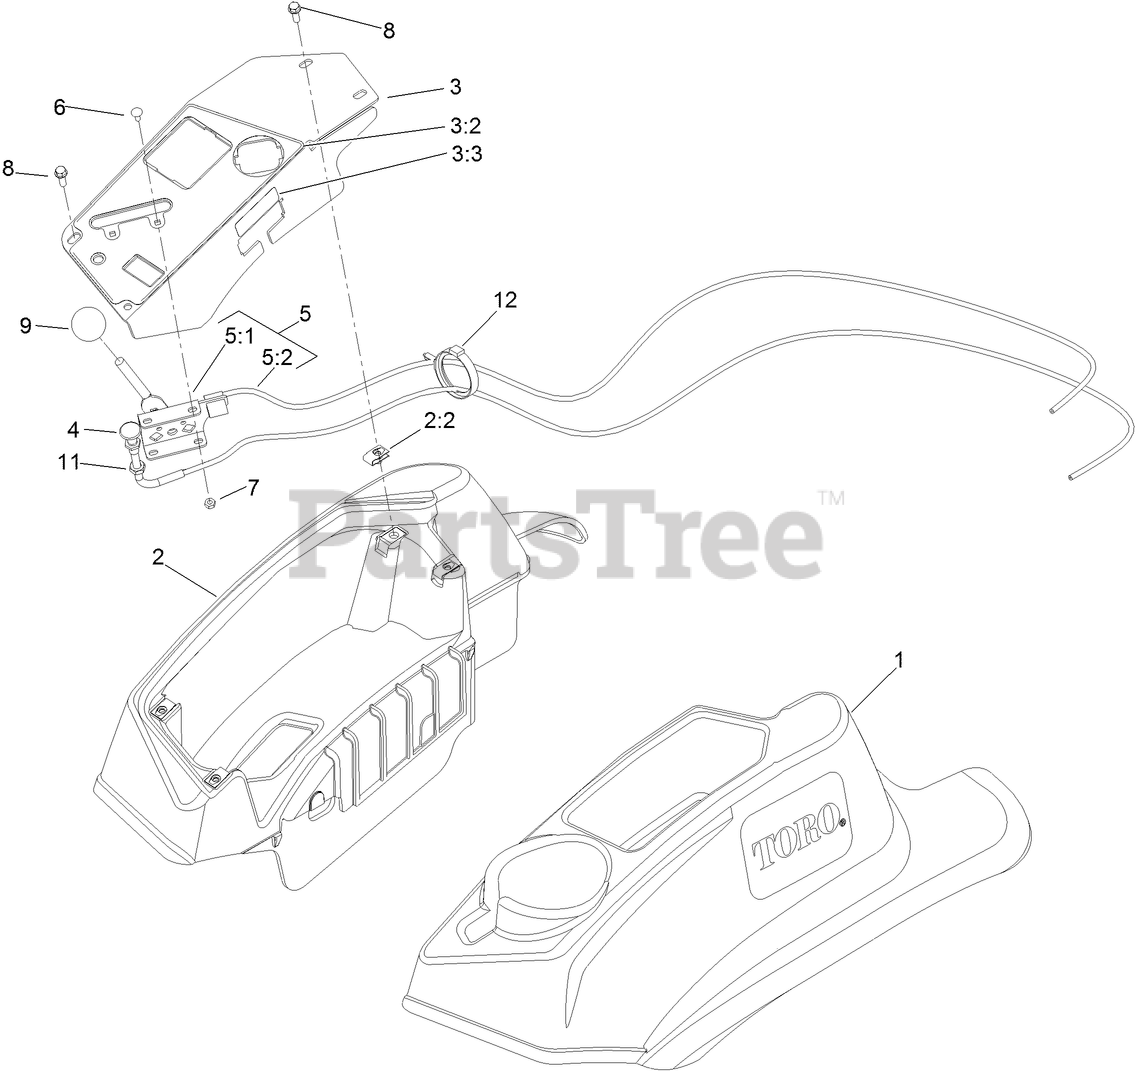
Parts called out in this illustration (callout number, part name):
1	CONSOLE-LH
2	RH CONSOLE ASM
3	CONTROL PANEL ASM
3:2	DECAL-CONTROL PANEL
3:3	DECAL-FUSES
4	CONTROL-CHOKE
5	THROTTLE CONTROL ASM
5:1	LEVER-THROTTLE
5:2	CABLE-THROTTLE
6	BOLT-CARR
7	NUT-LOCK, NI
8	SCREW-HWH
9	KNOB-BALL
11	NUT-HJ
12	CLAMP-HARNESS
